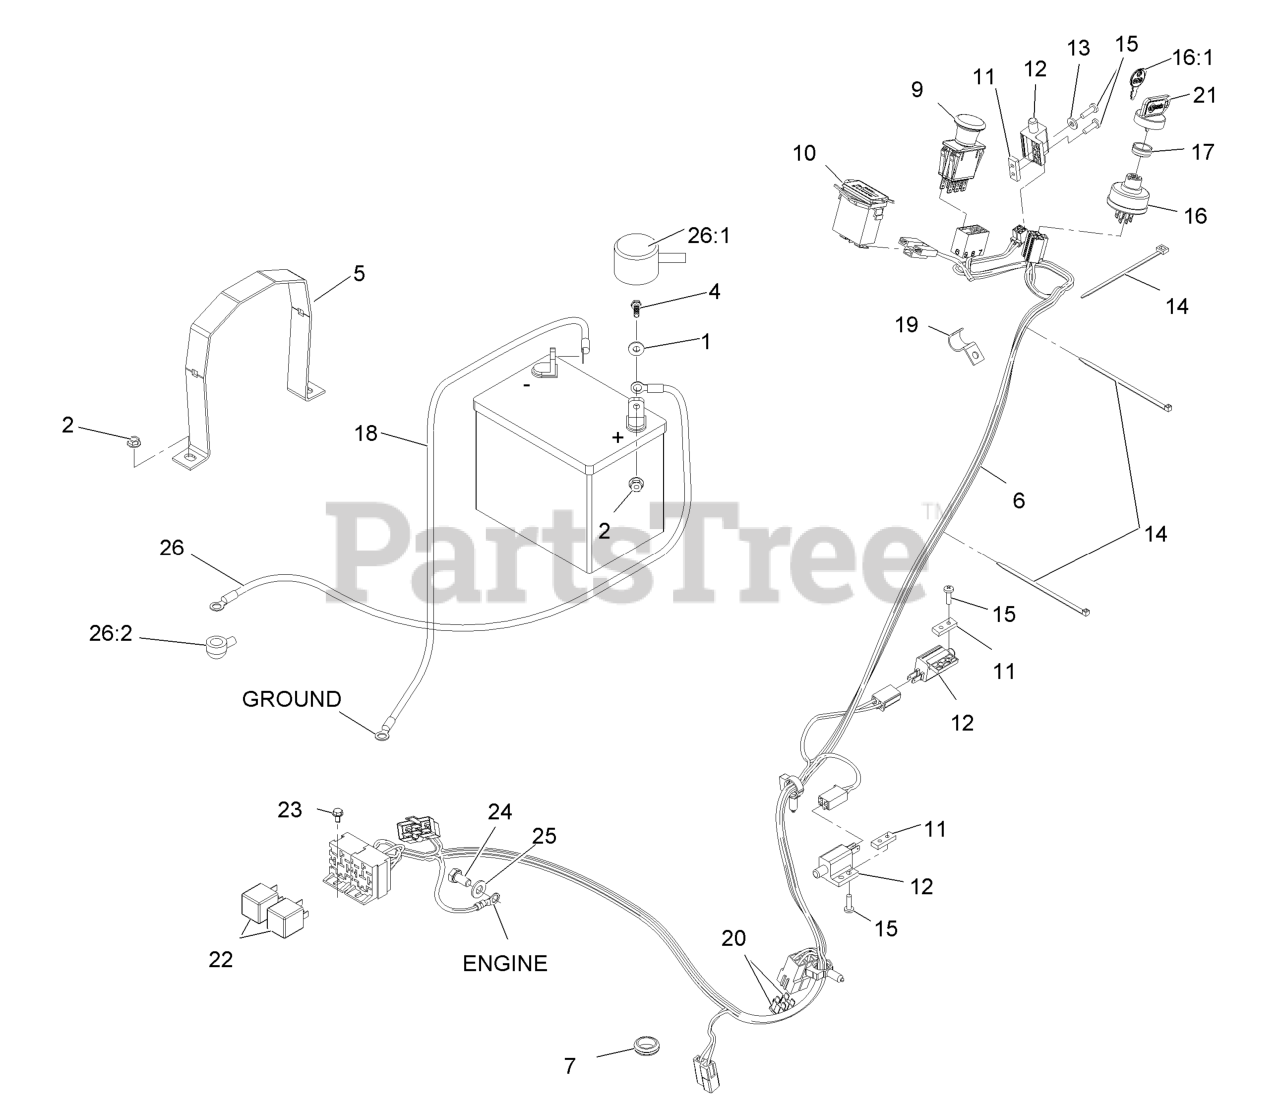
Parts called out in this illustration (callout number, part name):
1	WASHER-FLAT
4	SCREW-HH
5	STRAP,BATTERY HOLDDOWN
6	HARNESS-WIRE, TTX
7	GROMMET
9	SWITCH-PTO
10	METER-HOUR
11	PLATE-TAPPED
12	SWITCH-OPEN, NORMALLY
13	WASHER-FLAT
14	TIE-PLASTIC
15	SCREW-PPH
16:1	KEYS-IGNITION (SPARE PAIR
17	NUT-SWITCH, IGNITION
18	WIRE-GROUND
19	CLIP-HALF, LOOM
20	FUSE-BLADE TYPE, 20 AMP
21	KEY-IGNITION
23	SCREW-HWH
24	SCREW-HH
25	WASHER-PLAIN
26	POSITIVE BATTERY CABLE AS
26:1	INSULATOR-BATTERY
26:2	INSULATOR-SOLENOID
